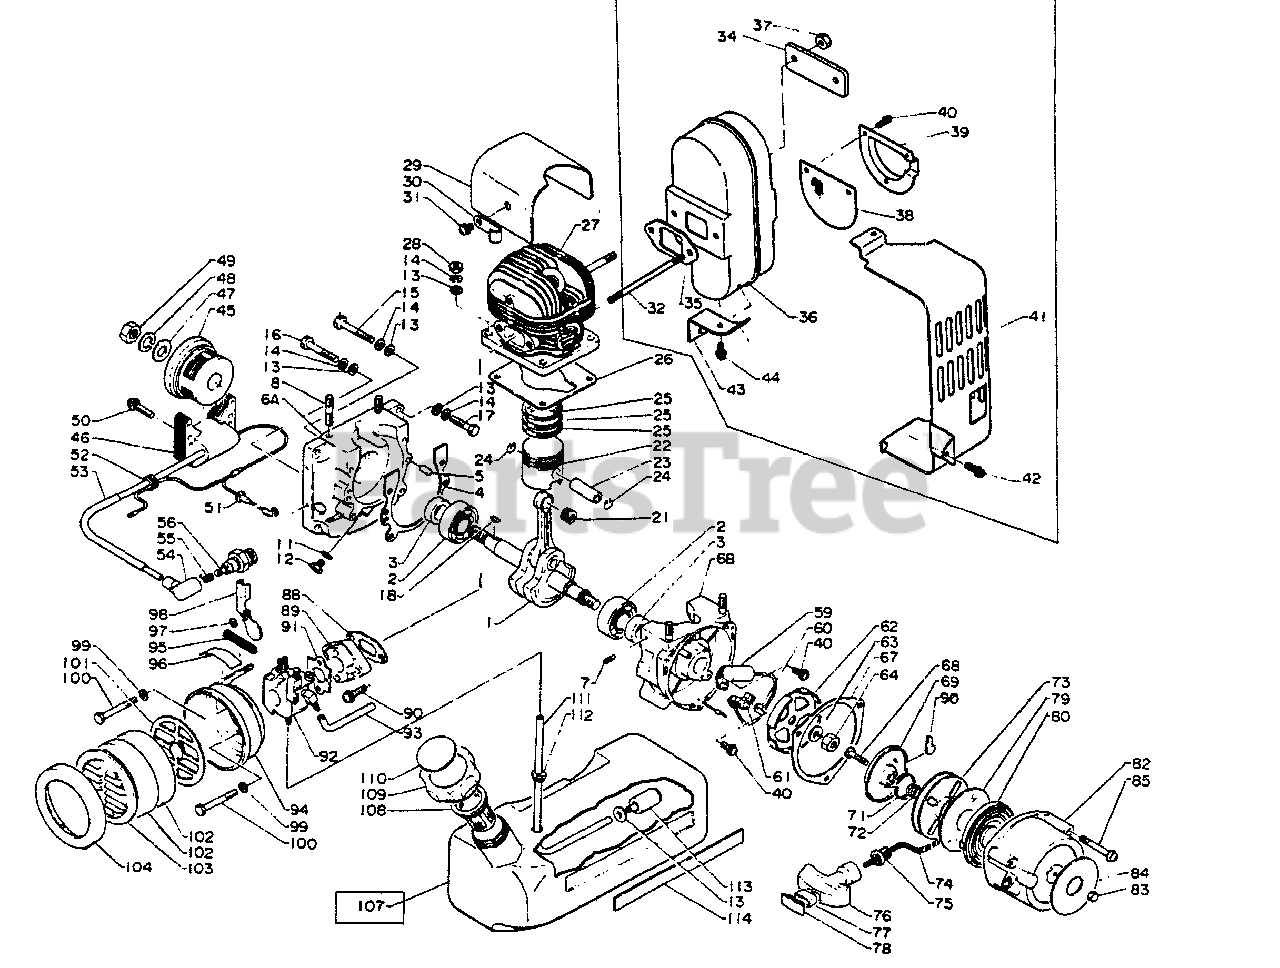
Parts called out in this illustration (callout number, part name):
1	CRANKSHAFT ASSY
2	BEARING, BALL - 6202
3	SEAL, OIL
4	GASKET, CRANKCASE
5	PIN - LOCATING
6	CRANKCASE KIT
6A	CRANKCASE KIT
7	CONNECTOR
12	BOLT, DRAIN
13	WASHER - 6
14	LOCKWASHER - 6
15	BOLT
16	BOLT
17	BOLT - 6X25
21	BEARING, NEEDLE
22	PISTON
23	PIN, PISTON
24	RING, RETAINING - 8
25	RING, PISTON
26	GASKET, CYLINDER
27	CYLINDER
28	LOCKNUT - 6
29	SHIELD, CYLINDER
31	BOLT - 6X10
32	STUD
35	GASKET, EXHAUST
36	MUFFLER
37	LOCKNUT - 6
38	SCREEN, SPARK ARRESTOR
39	GUIDE, EXHAUST
40	SCREW - 4X10
41	COVER, EXHAUST
42	SCREW - 5X12
43	Supporter
44	SCREW - 5X10
45	FLYWHEEL
46	COIL, IGNITION
48	LOCKWASHER
50	SCREW - 5X25
54	CAP, SPARK PLUG
55	TERMINAL, SPARK PLUG CAP
56	SPARK PLUG -- BM-6A
59	CONDENSER
61	CONTACT POINT SET
62	CATCHER, PAWL
63	WASHER, CLUTCH
67	GASKET, STARTER
69	PLATE, FRICTION
70	PAWL, STARTER
71	SPRING, RETURN
72	SPRING
73	REEL, ROPE
74	ROPE, STARTER - 4X880
75	GUIDE, ROPE
76	GRIP, STARTER
77	RING, RETAINING
79	PLATE, STARTER
80	SPRING, REWIND
82	CASE, STARTER
83	NUT - 5 -- CAP
84	LABEL - ECHO
85	SCREW - 5X40
88	GASKET, INTAKE
89	INSULATOR, INTAKE
90	SCREW - 6X25
91	GASKET, INTAKE
92	CARBURETOR WA-55
93	PIPE - IMPULSE
94	CASE, AIR FILTER
95	GROMMET
96	LABEL - CHOKE
97	WASHER
98	SHUTTER, CHOKE
99	WASHER - 5
100	BOLT
101	RETAINER, AIR FILTER
102	FILTER, AIR
103	COVER, AIR FILTER
104	COVER, AIR FILTER
107	TANK, FUEL
108	STRAINER
109	CAP ASSY
110	LABEL - FUEL MIX
111	PIPE, FUEL - SPIRAL
112	GROMMET
113	FILTER, FUEL
114	LABEL - NAME
